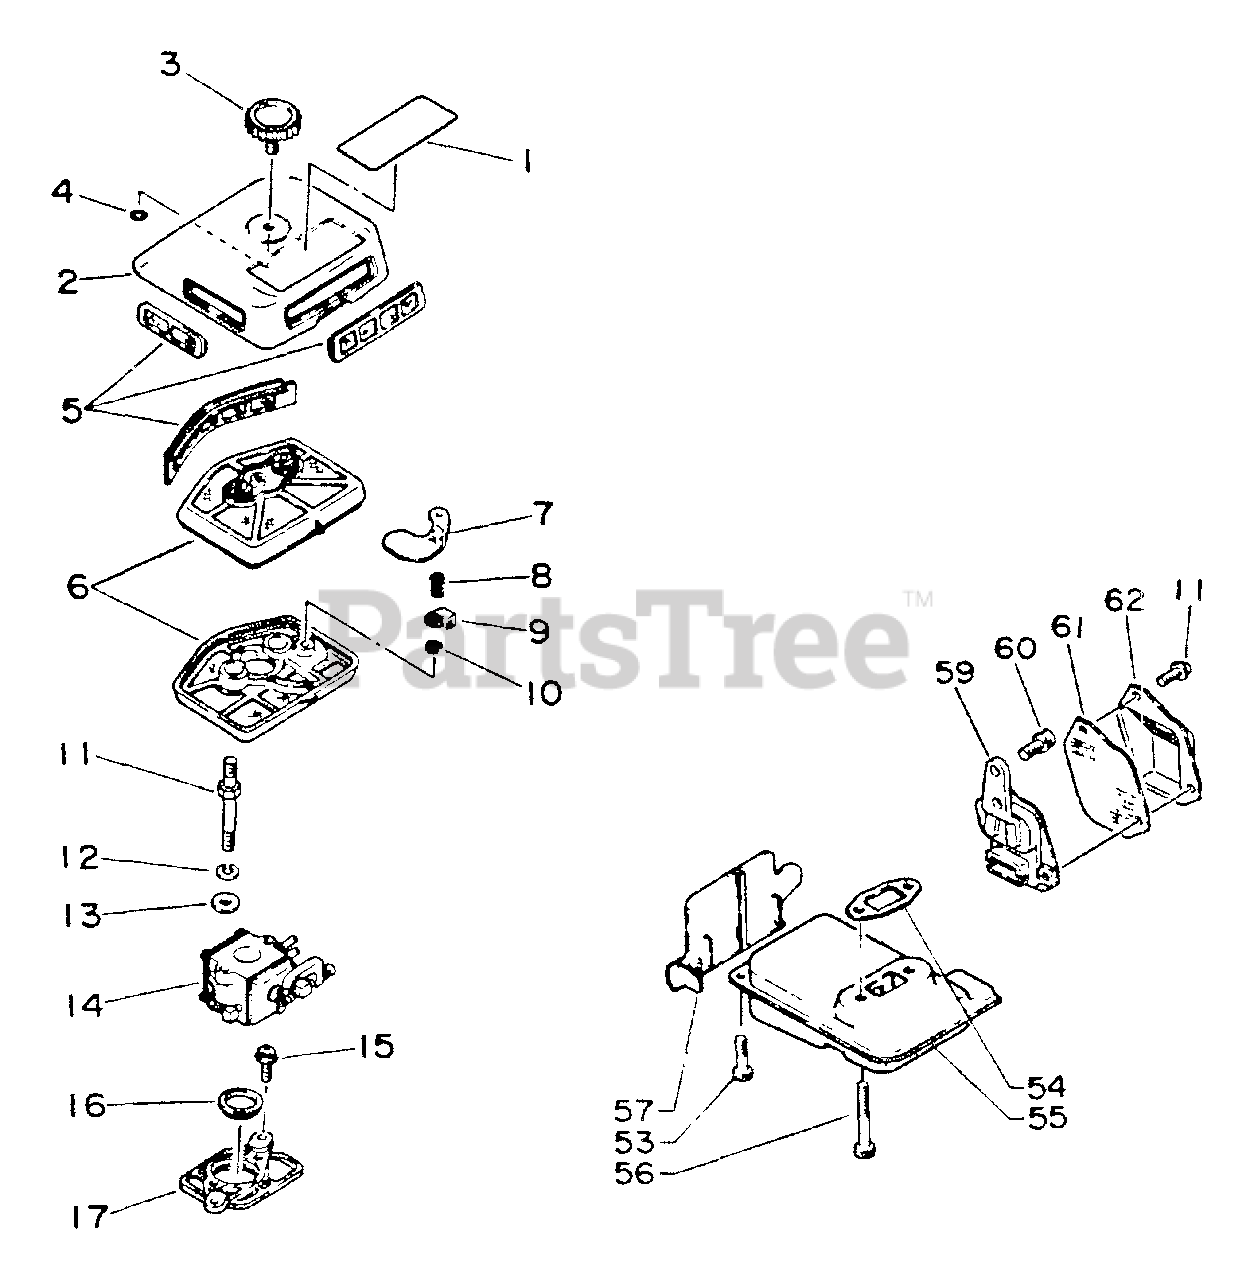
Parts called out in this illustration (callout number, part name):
1	LABEL - MODEL
2	COVER, AIR FILTER
3	THUMBSCREW
4	O-RING - 3
5	DEBRIS FILTER KIT
6	FILTER, AIR
7	SHUTTER, CHOKE
8	SPRING
9	LEVER, CHOKE
10	RING, RETAINING - 3
12	LOCKWASHER - 5
13	WASHER - 5
14	CARBURETOR WA-133
15	SCREW - 4X12
16	SEAL
17	ADAPTOR, CARBURETOR
53	SCREW - 5X20
54	GASKET, EXHAUST
55	MUFFLER
56	SCREW - 5X50
57	INSULATOR
59	ADAPTOR
60	SCREW - 5X12
61	SCREEN, SPARK ARRESTOR
62	GUIDE, EXHAUST
